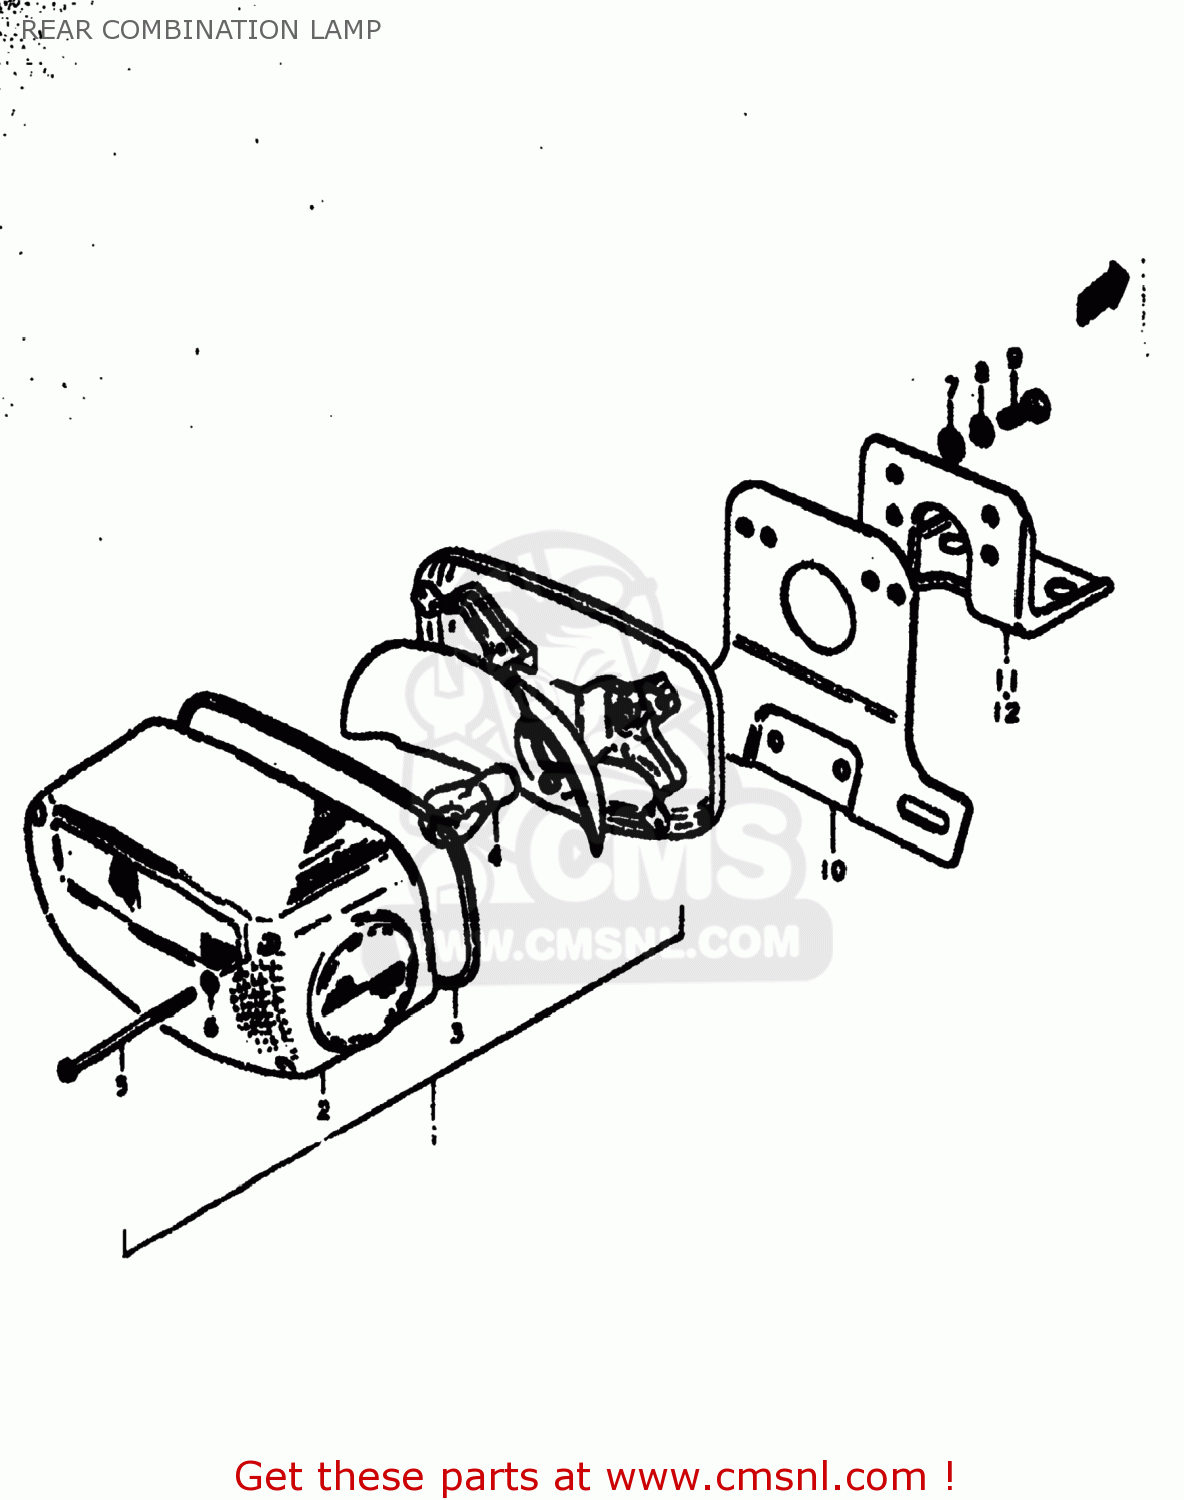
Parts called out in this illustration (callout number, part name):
1	LAMP ASSEMBLY,REAR COMBINATION
2	LENS,REAR COMBINATION LAMP
3	GASKET (NAS)
4	BULB(12V23W)
5	SCREW
6	GASKET (NAS)
7	WASHER
8	LOCK WASHER
9	BOLT
10	BRACKET,LICENSE PLATE
11	BRACKET,LICENSE PLATE
12	BRACKET,LICENSE PLATE
